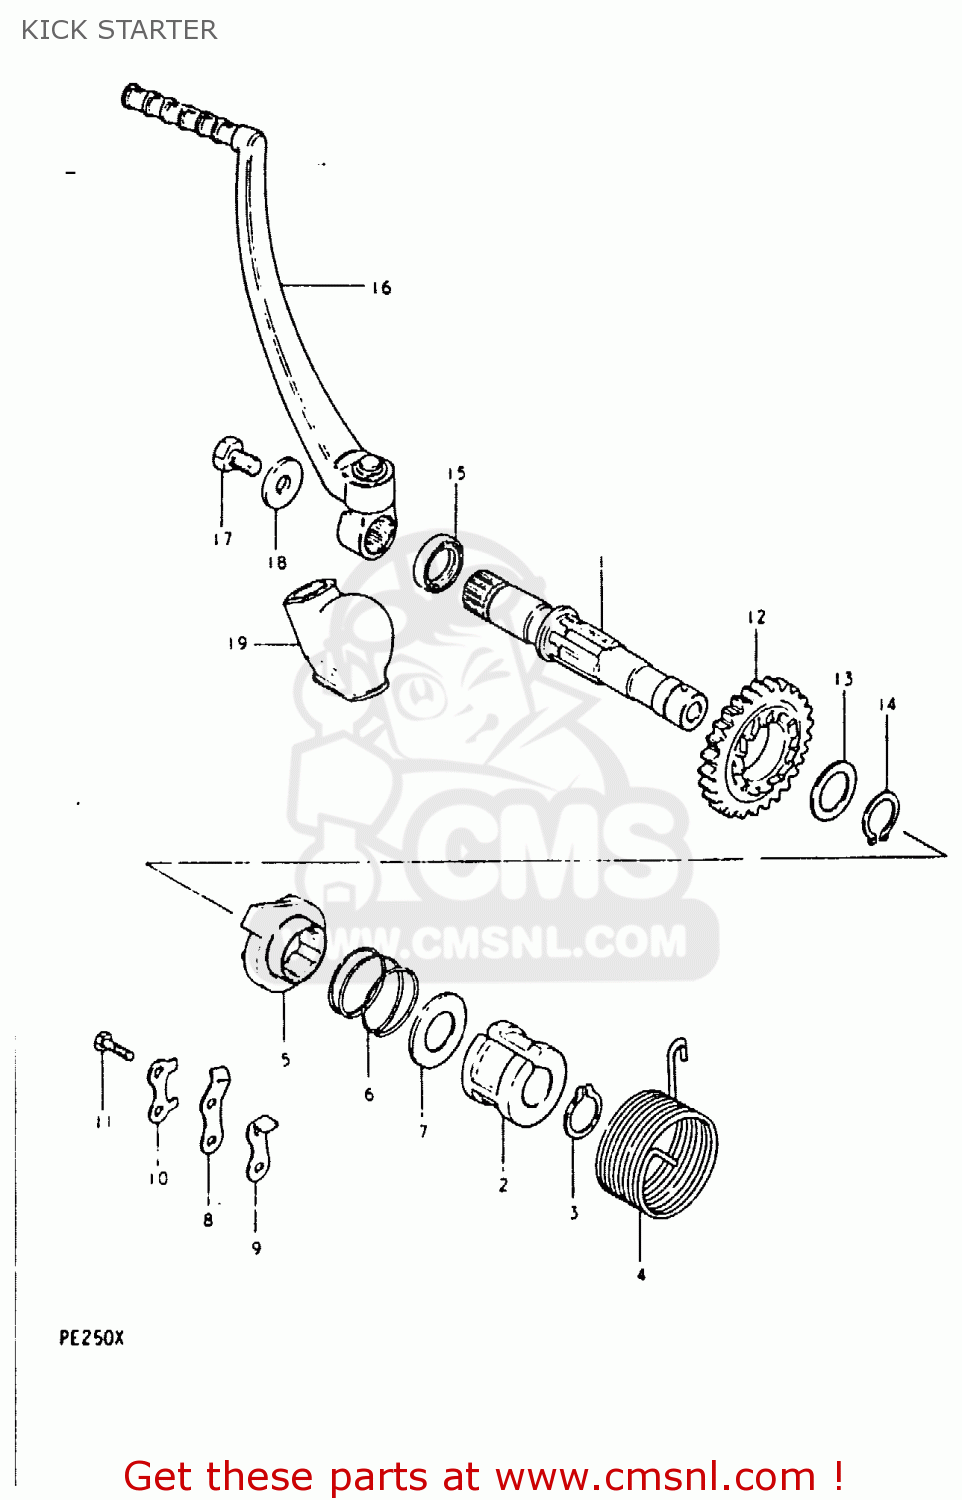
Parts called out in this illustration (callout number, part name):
1	SHAFT,KICK STARTER
2	GUIDE,KICK STARTER SFT SPRING
3	CIRCLIP
4	SPRING
5	STARTER,KICK
6	SPRING
7	WASHER
8	GUIDE,KICK STARTER
9	STOPPER,KICK STARTER
10	WASHER
11	BOLT
12	GEAR,KICK STARTER DRIVE
13	SHIM
14	CIRCLIP
15	SEAL,OIL(20X27X5)
16	LEVER ASSEMBLY,KICK STARTER
17	BOLT
18	WASHER(8.2X23X3.2)
19	COVER,KICK LEVER JOINT
